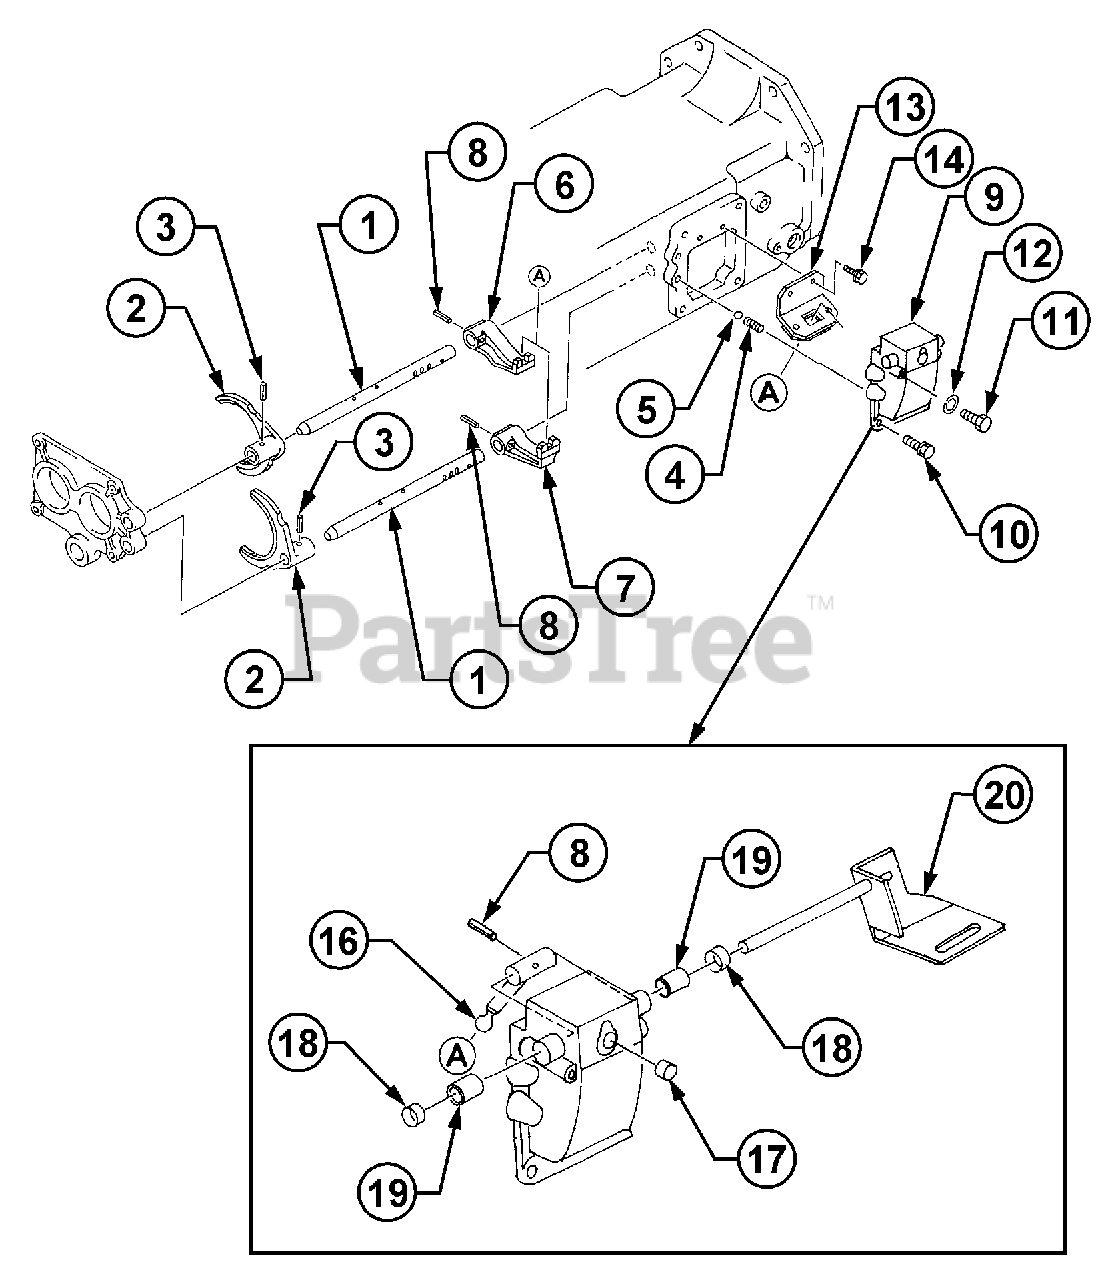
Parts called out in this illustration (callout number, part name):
9	Holder, Lever
10	Bolt, w/Washer
14	Bolt, w/Washer
